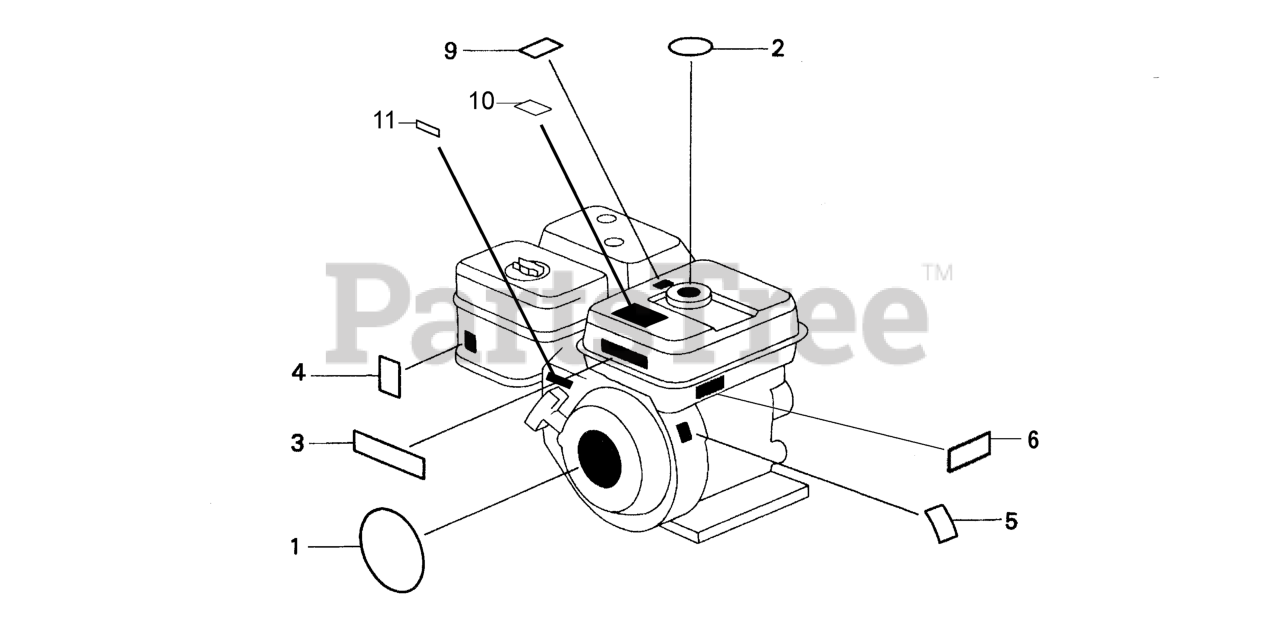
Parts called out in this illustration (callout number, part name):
1	EMBLEM
2	MARK, CAUTION (EXTERNAL)
3	LABEL, CAUTION (ENGLISH, ETC.)
4	MARK, CHOKE
5	LABEL, SPECIFICATION (EXTERNAL)
6	MARK, OIL ALERT (ENGLISH)
9	LABEL, FUEL CAUTION
